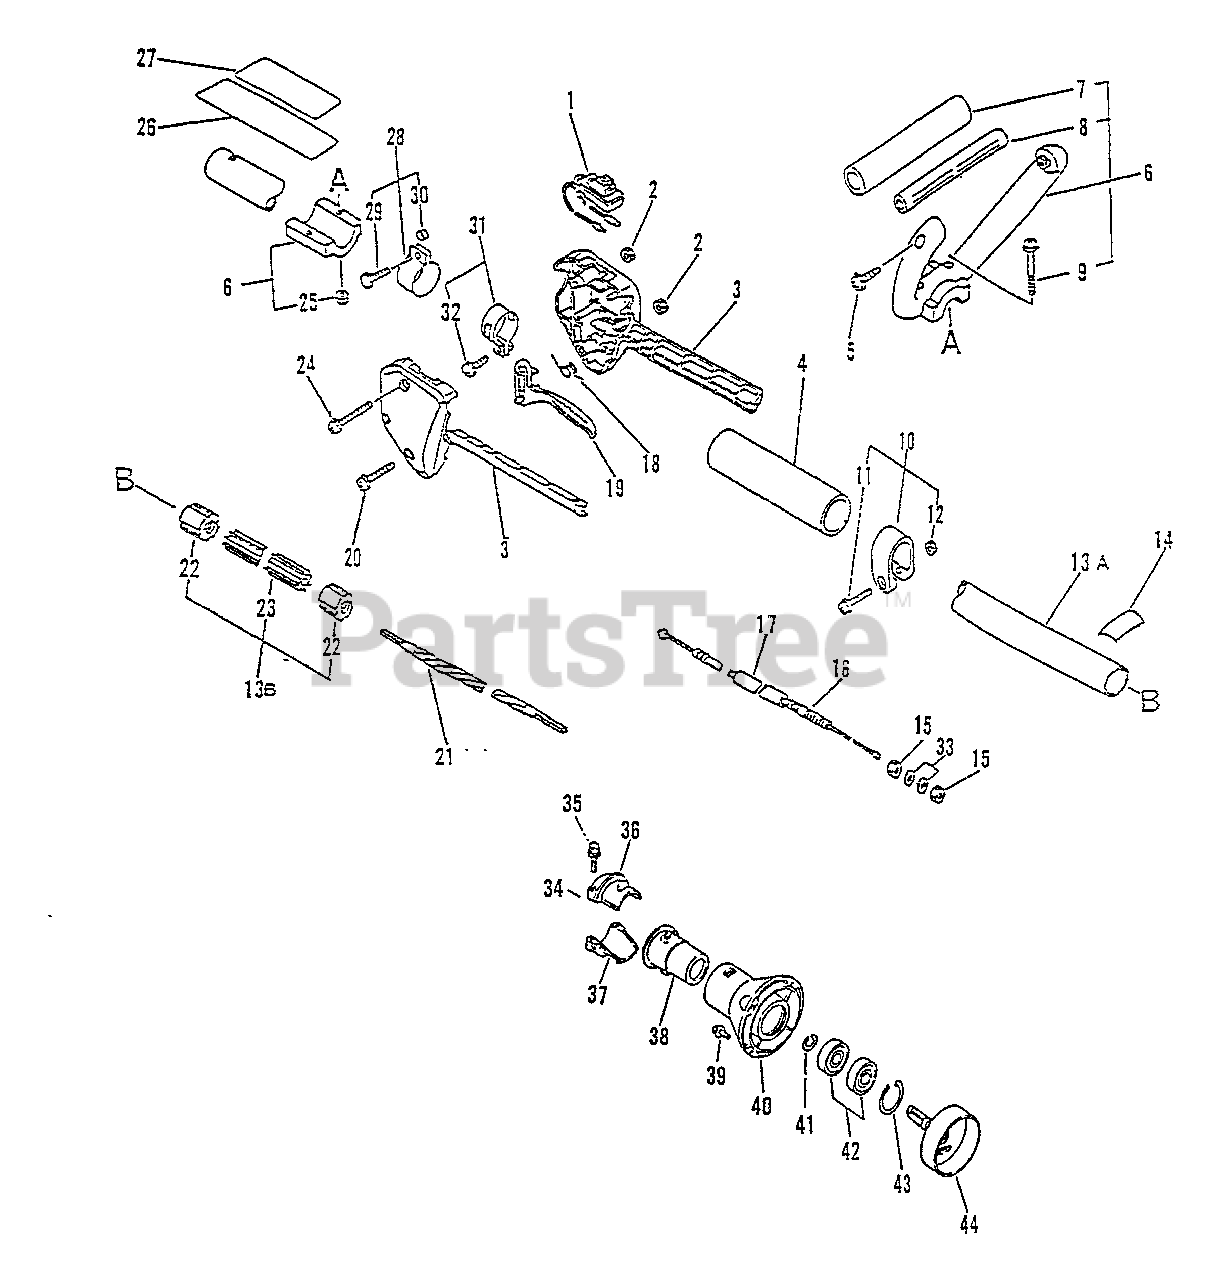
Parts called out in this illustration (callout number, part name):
1	IGNITION SWITCH ASSY
3	CONTROL HANDLE KIT
4	GRIP, HANDLE
5	SCREW - 5X30
6	LOOP HANDLE ASSY
7	GRIP, HANDLE
9	SCREW - 6X35
10	CLAMP KIT
11	SCREW - 5X30
13	MAIN PIPE ASSY
14	LABEL - ALIGNMENT
16	CABLE, THROTTLE
17	TUBE - VINYL
18	SPRING, TRIGGER
19	TRIGGER, THROTTLE
20	SCREW - 5X25
21	DRIVESHAFT - FLEXIBLE
23	LINER - FLEXIBLE
24	SCREW - 5X35
25	LOCKNUT - 6
26	LABEL - CAUTION
27	LABEL - CAUTION
28	CLAMP
29	BOLT - 5X18
31	CLAMP KIT
32	SCREW - 5X14
33	WASHER - 6
34	HOLDER KIT
35	BOLT - 5X25
36	CLAMP, MAIN PIPE - UPPER
37	CLAMP, MAIN PIPE
39	SCREW - 5X16
40	CASE, CLUTCH - GRAY
41	RING, RETAINING - 12
42	BEARING, BALL - 6001
43	RING, RETAINING - 28
44	DRUM, CLUTCH
